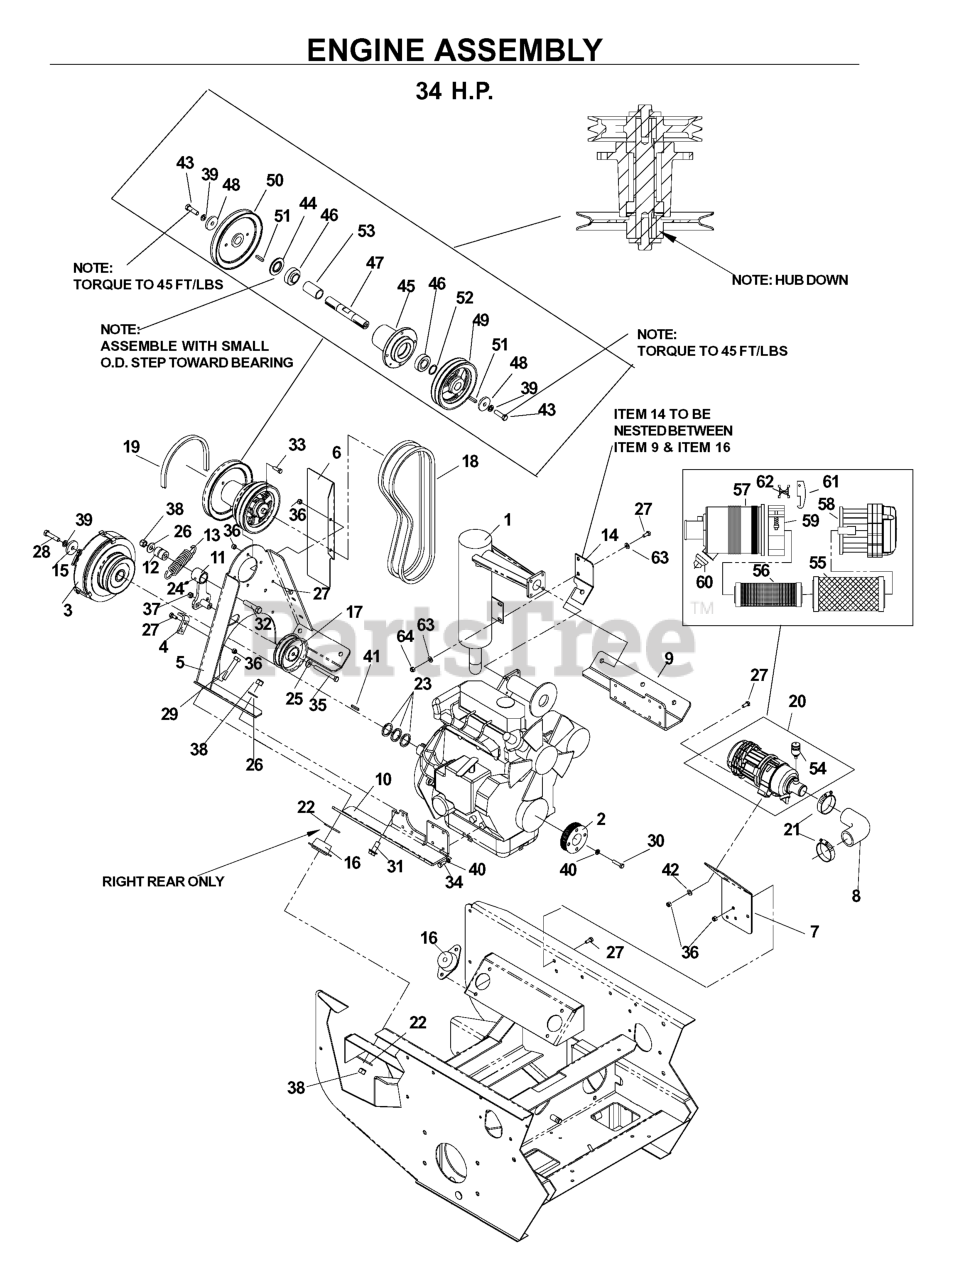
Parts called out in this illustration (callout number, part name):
1	MUFFLER ASSY
2	ENGINE SHEAVE
3	CLUTCH
4	RESTRAINT
5	JACKSHAFT MOUNT WELDMENT
6	HEAT SHIELD
7	MOUNTING BRACKET
8	AIR FILTER HOSE
9	ENGINE MOUNT-LT
10	ENGINE MOUNT-RT
11	ARM WELDMENT
14	MUFFLER MT BLACK PAINTED
15	SPINDLE WASHER
17	IDLER, PRIMARY
18	ENGINE BELT, PRIMARY
19	ENGINE, BELT MULE
20	AIR FILTER ASSY
21	CLAMP, AIR HOSE
22	ISOLATOR WASHER
23	BUSH 1-1/8 X 10 GA ZD
24	ZERK
25	WASHER 3/8 SAE FLAT
26	WASHER 1/2 FLAT
27	HCS 5/16C X 3/4
28	BOLT 7/16F X 2 1/2
29	HCS 1/2C X 2 3/4
30	HTB M8-1.125 X 25MM
31	HCS 1/2C X 1 1/4 SERRATED HEAD
32	HEX SCREW 1/2-13 X 2.5" GR 5
33	HCS 5/16C X 1
35	HCS 3/8-16 X 3-1/2 GR5 ZD
36	NUT 5/16 NYLOC
37	NUT 3/8-16 NYLOC
38	NUT 1/2-13 HEX NYLOC ZD
39	WASHER 7/16 LOCK
40	WASHER.LOCK.HVY.HLCL.SPR.5/16
41	KEY 1/4" SQ X 1 7/8"
42	WASHER 5/16 FLAT
43	HCS 7/16F X 1 1/2
44	COMBO SPACER
45	HOUSING, DIE CAST
46	BEARING
48	SPINDLE WASHER
51	KEY 1/4 SQ X 1 1/8
52	BUSHING.MACHINE.18.GAUGE
55	AIR FILTER
56	SAFETY ELEMENT
57	BODY, STRAIGHT
58	PRECLEANER ASM
59	MOUNTING BRACKET
63	WASHER, 3/8 DISC SPRING SPEC
64	NUT 5/16C WHIZ
539106327	STUB SHAFT
539109177	MANIFOLD GASKET
